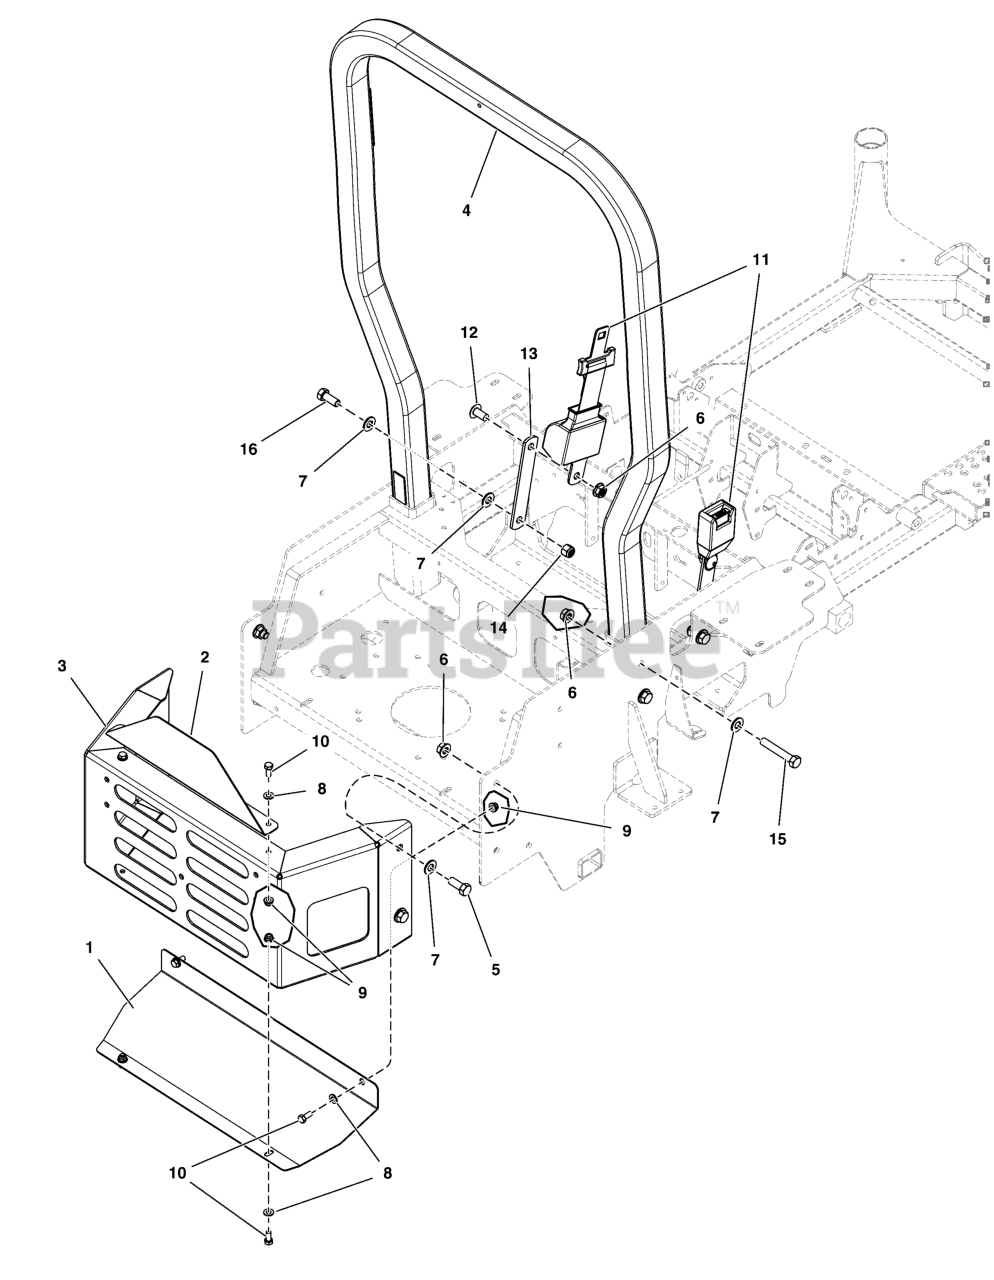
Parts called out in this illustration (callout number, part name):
1	PLATE, HEAT SHIELD, S125XT - BLACK
2	PLATE, CARB PROTECTOR - RED
3	WELD, BUMPER, S125XT - RED
4	ROLL BAR
5	BOLT, 1/2-13 X 1-1/4 GD5 CZ
6	NUT, Hex Flange, Nylock, 1/2-13
7	WASHER, 1/2 SAE
8	WASHER, 5/16" SAE
9	NUT, 5/16-18 HEX NYLOCK FLANGE NUT
10	BOLT, 5/16-18 X 3/4 GD5
11	SEAT BELT, RETRACTING - ASSM - RED
12	SCREW, 1/2 - 13 X 1.00 SCHS
13	BAR, MOUNT, SEAT BELT, IS700Z - BLK
14	NUT, 1/2-13 HEX NYLON LOCK
15	BOLT, 1/2-13 X 3" GD5 CZ
16	BOLT, 1/2-13 X 1-1/2 GD5 CZ
